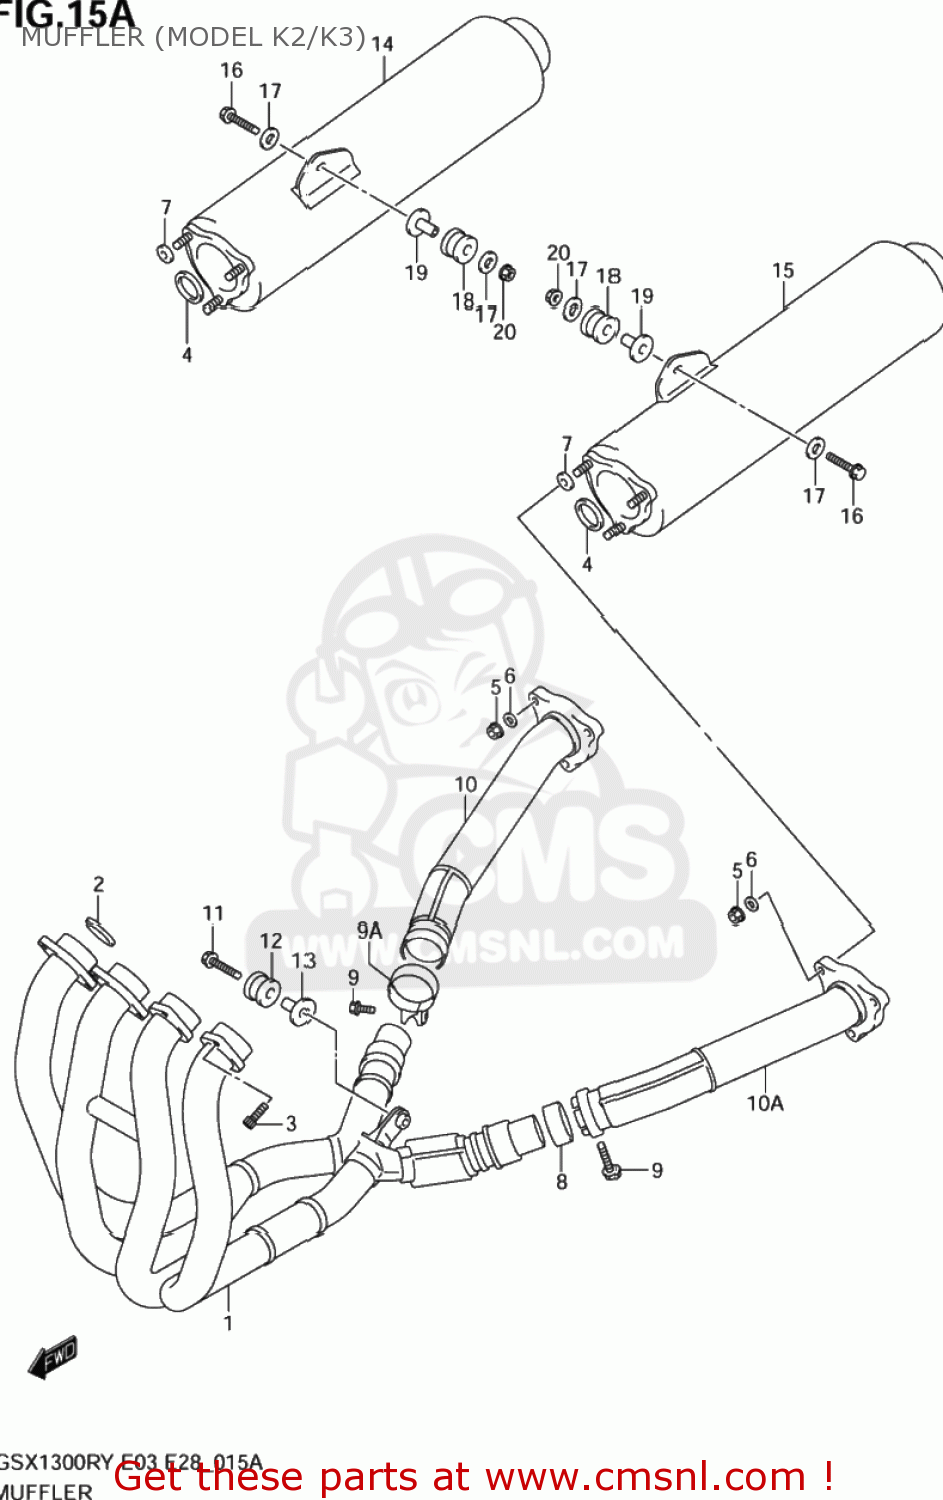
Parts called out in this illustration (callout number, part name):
1	EXHAUST
2	GASKET,EXHAUST PIPE (NAS)
3	BOLT
4	GASKET,MUFFLER JOINT
5	NUT
6	WASHER(8.5X18X1.6)
7	O RING(D:1.9,ID:7.8)
8	CONNECTOR,MUFFLER
9	BOLT
9A	CLAMP,CONNECTOR MUFFLER,R
10	PIPE,JOINT,R
10A	PIPE,JOINT,L
11	BOLT 8X45
12	CUSHION
13	SPACER(8.6X12X24.2)
14	BODY,MUFFLER,R
15	BODY,MUFFLER,L
16	BOLT(8X45)
17	WASHER(8.5X28X1.5)
18	CUSHION
19	SPACER(8.6X12X27.1)
20	NUT
